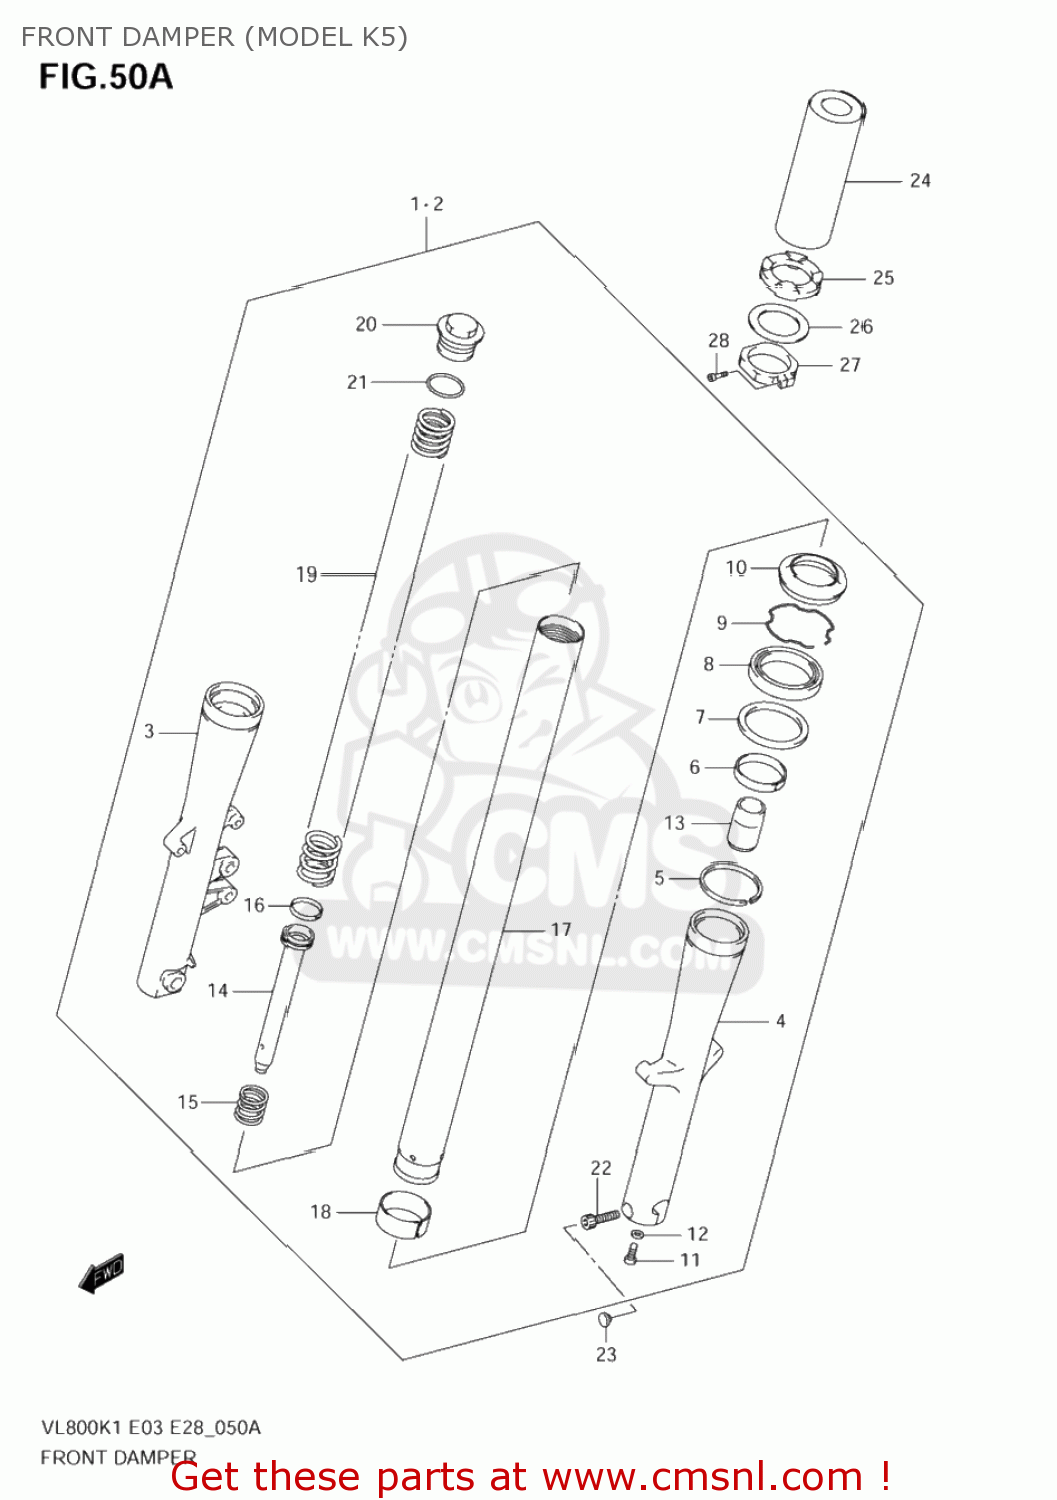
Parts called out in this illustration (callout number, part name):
1	DAMPER ASSY,FR FORK,R
2	DAMPER ASSY,FR FORK,L
3	TUBE,OUTER,R
4	TUBE,OUTER,L
5	GUIDE,CASE
6	BUSH,GUIDE
7	SPACER,SEAL
8	SEAL,OIL
9	CIRCLIP,FORK OIL SEAL
10	SEAL,DUST
11	BOLT
12	GASKET (NAS)
13	PIECE,OIL LOCK
14	SEAT,PIPE
15	SPRING,REBOUND
16	RING,PISTON
17	TUBE,INNER
18	BUSH,SLIDE
19	SPRING,FR
20	BOLT,FORK
21	O RING
22	BOLT
23	CAP(OD:12)
24	CASE,UNDER
25	SEAT,RUBBER
26	WASHER
27	SPACER
28	BOLT
